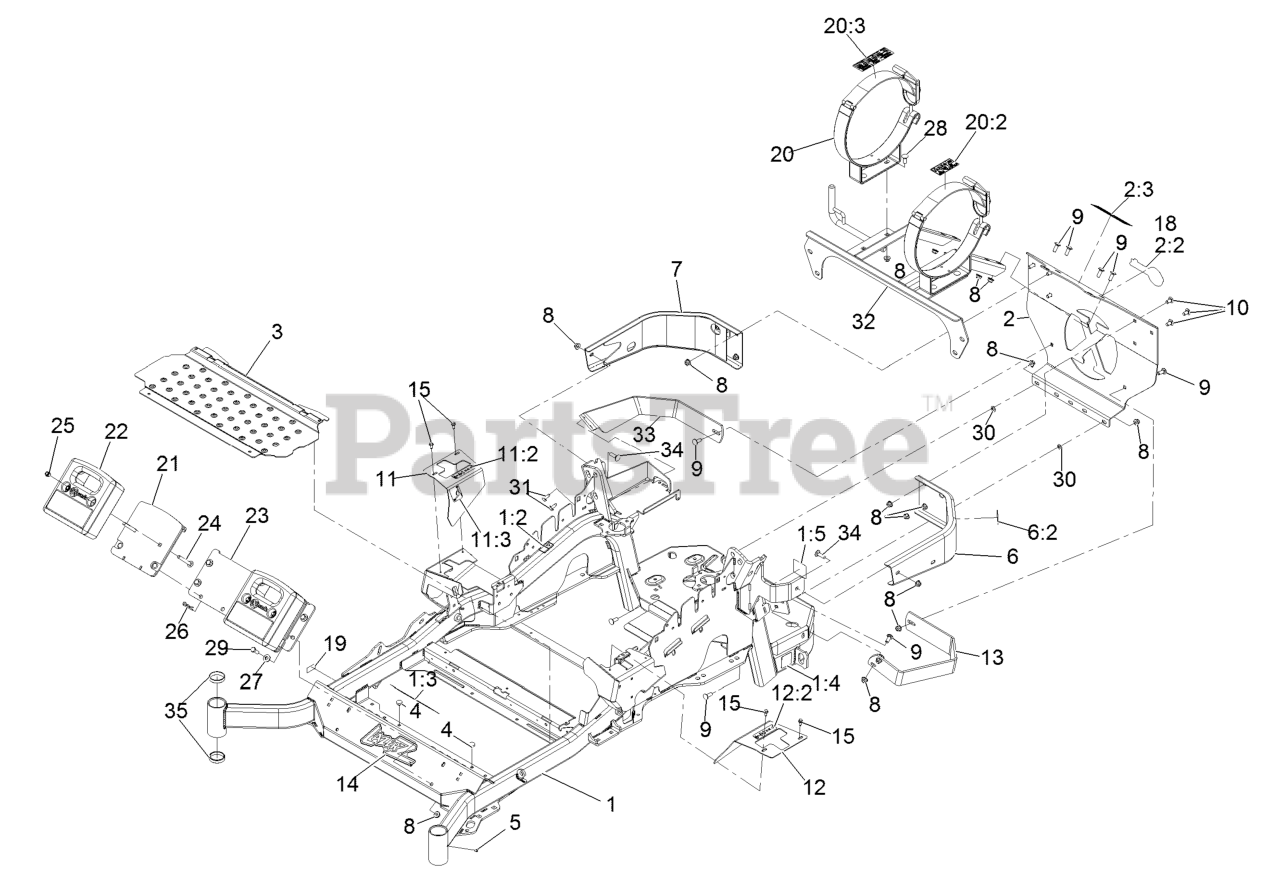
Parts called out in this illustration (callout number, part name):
1	MAINFRAME ASM
1:2	DECAL-WARNING, SLOPE
1:3	DECAL-WARNING
1:4	DECAL-HAZARD, PINCHED FINGER
1:5	DECAL-SPARK ARRESTER
2	REAR GUARD-LP W/DECALS
2:3	Decal-LPG Fuel Tank Replacement
6	LH BUMPER ASM
6:2	DECAL-WARNING
7	BUMPER-RH
8	NUT-HF, NI
9	SCREW-CARR
10	SCREW-CARR
11	RH MOTION CONTROL COVER ASM
11:2	DECAL-CONTROL, MOTION
11:3	DECAL-PARK BRAKE, CE
12	LH MOTION CONTROL COVER ASM
12:2	DECAL-CONTROL, MOTION
13	GUARD-MUFFLER
14	DECAL,LAZER MODEL
15	SCREW-HWH
19	Decal-Patent Ttco.Com
20	TANK BRACKET ASM (SET)
20:2	Decal-LPG Warning
20:3	Decal-LPG Tank Spec
21	WLD,WEIGHT MOUNT
22	WEIGHT,CAST 36LB
23	PLATE,WEIGHT ASM MOUNT
24	SCREW-CARR
25	NUT-LOCK, NI
26	PIN-HAIR
27	WASHER-BELLEVILLE
28	BOLT-CARR
29	SCREW-HH
30	NUT-PUSH
31	Screw-HWH 5/16-18 X 3/4 Tf
32	SUPPORT-TANK
33	STRAP-GUARD
34	BOLT-CARR
35	CUP-BEARING
